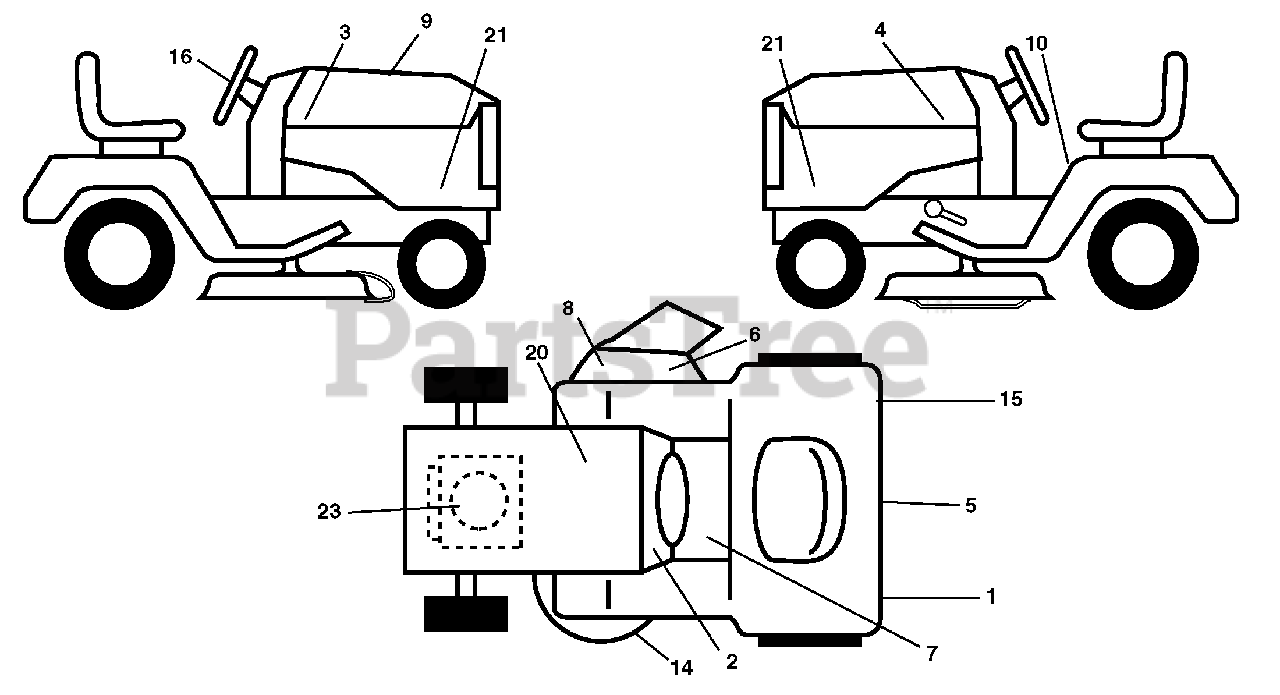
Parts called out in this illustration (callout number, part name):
1	Refl ector, LH
2	Decal Dash
3	Decal Hood Rh
4	Decal Hood LH
5	Decal Fender Logo
6	Decal Warning, Keep Hand Away
7	Decal Oper. Cruise Control
8	Decal Deck "B" 42"
9	Decal Replacement Hood
10	Decal Fender Danger
14	Decal V-Belt Schematic
15	Decal Refl ector, RH
16	Decal Ins Strg Whl
20	Decal Battery
21	Decal Side Panel Logo
23	Decal Engine
23	Decal By Pass Lt Hydro
23	Pad Footrest LH
23	Pad Footrest RH
23	Manual Operator's E&F
23	Manual Parts E&F
